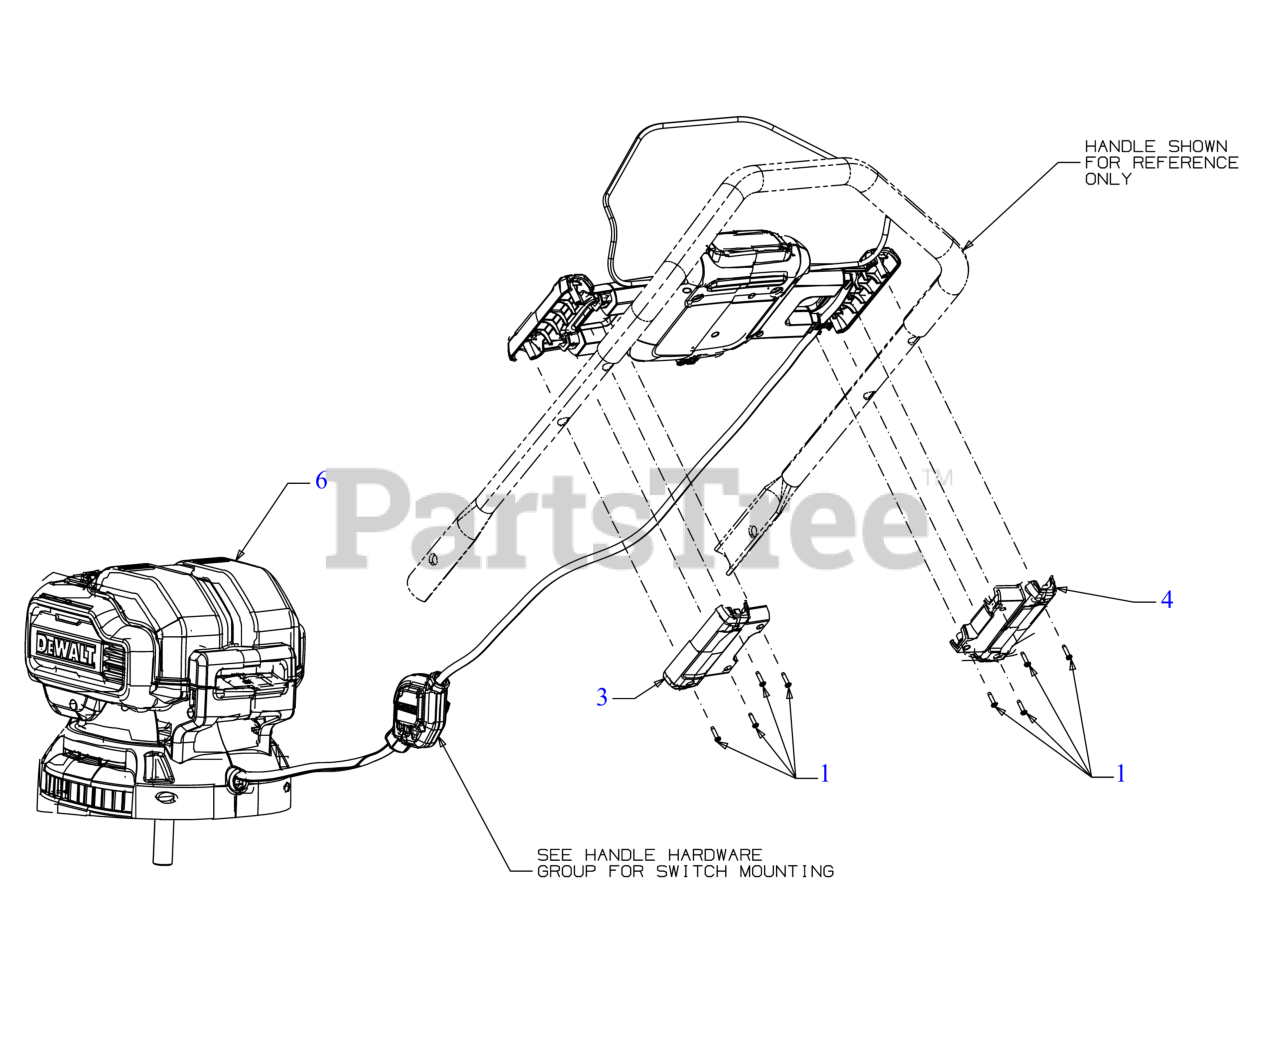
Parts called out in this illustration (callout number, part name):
1	SCREW-TAP PLASTIC #6-19 X 0.62
3	HANDLE PANEL COVER (REAR) (LH) (BLACK)
4	HANDLE PANEL COVER (REAR) (RH) (BLACK)
6	MOTOR/PANEL ASSEMBLY
